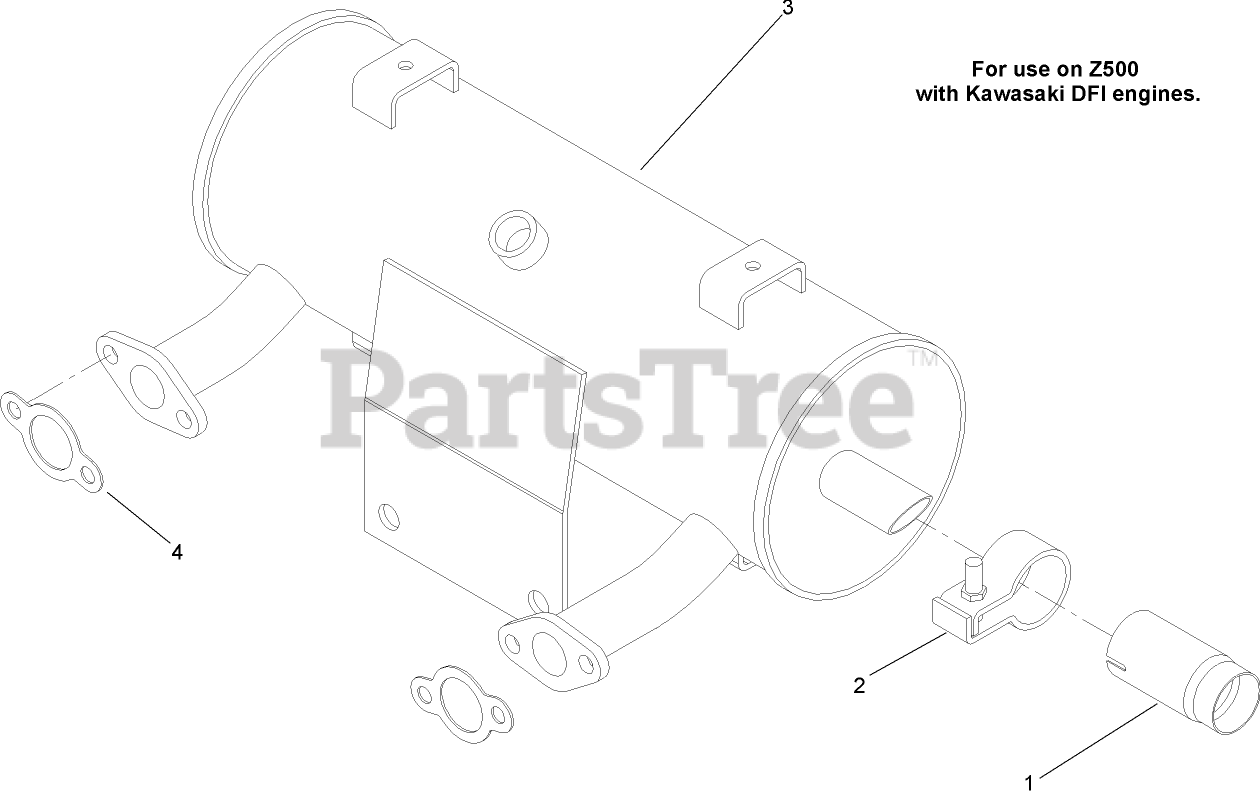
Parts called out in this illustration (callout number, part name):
1	ARRESTOR-SPARK
2	CLAMP-MUFFLER
3	MUFFLER
4	GASKET-EXHAUST
